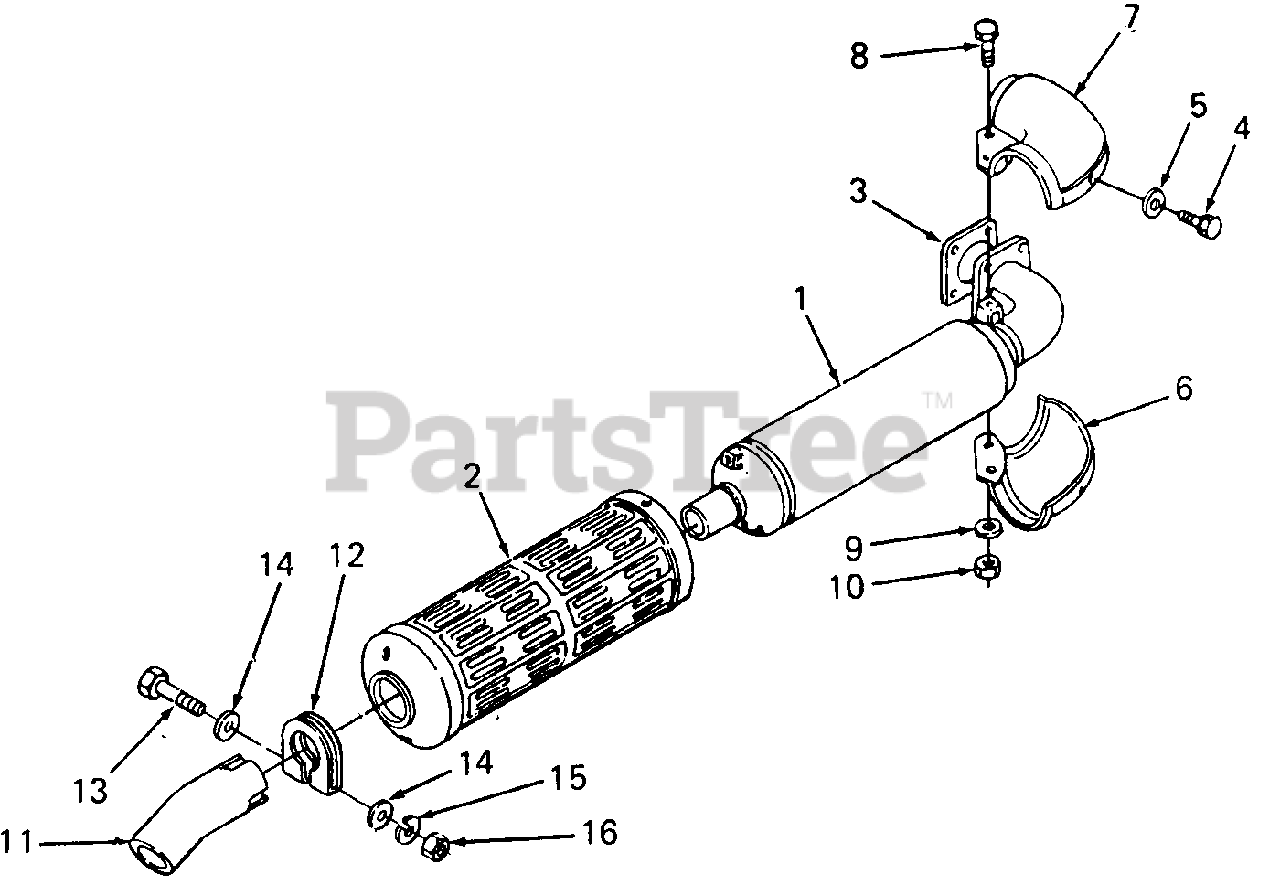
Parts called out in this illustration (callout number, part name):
2	Cover, Muffler
3	Gasket, Muffler
5	Washer, Plain
6	Cover, Muffler Flange
7	Cover w/Nut, Muffler Flange
8	Bolt
9	Washer, Spring
11	Pipe, Muffler
14	Washer, Plain
15	Washer, Plain
